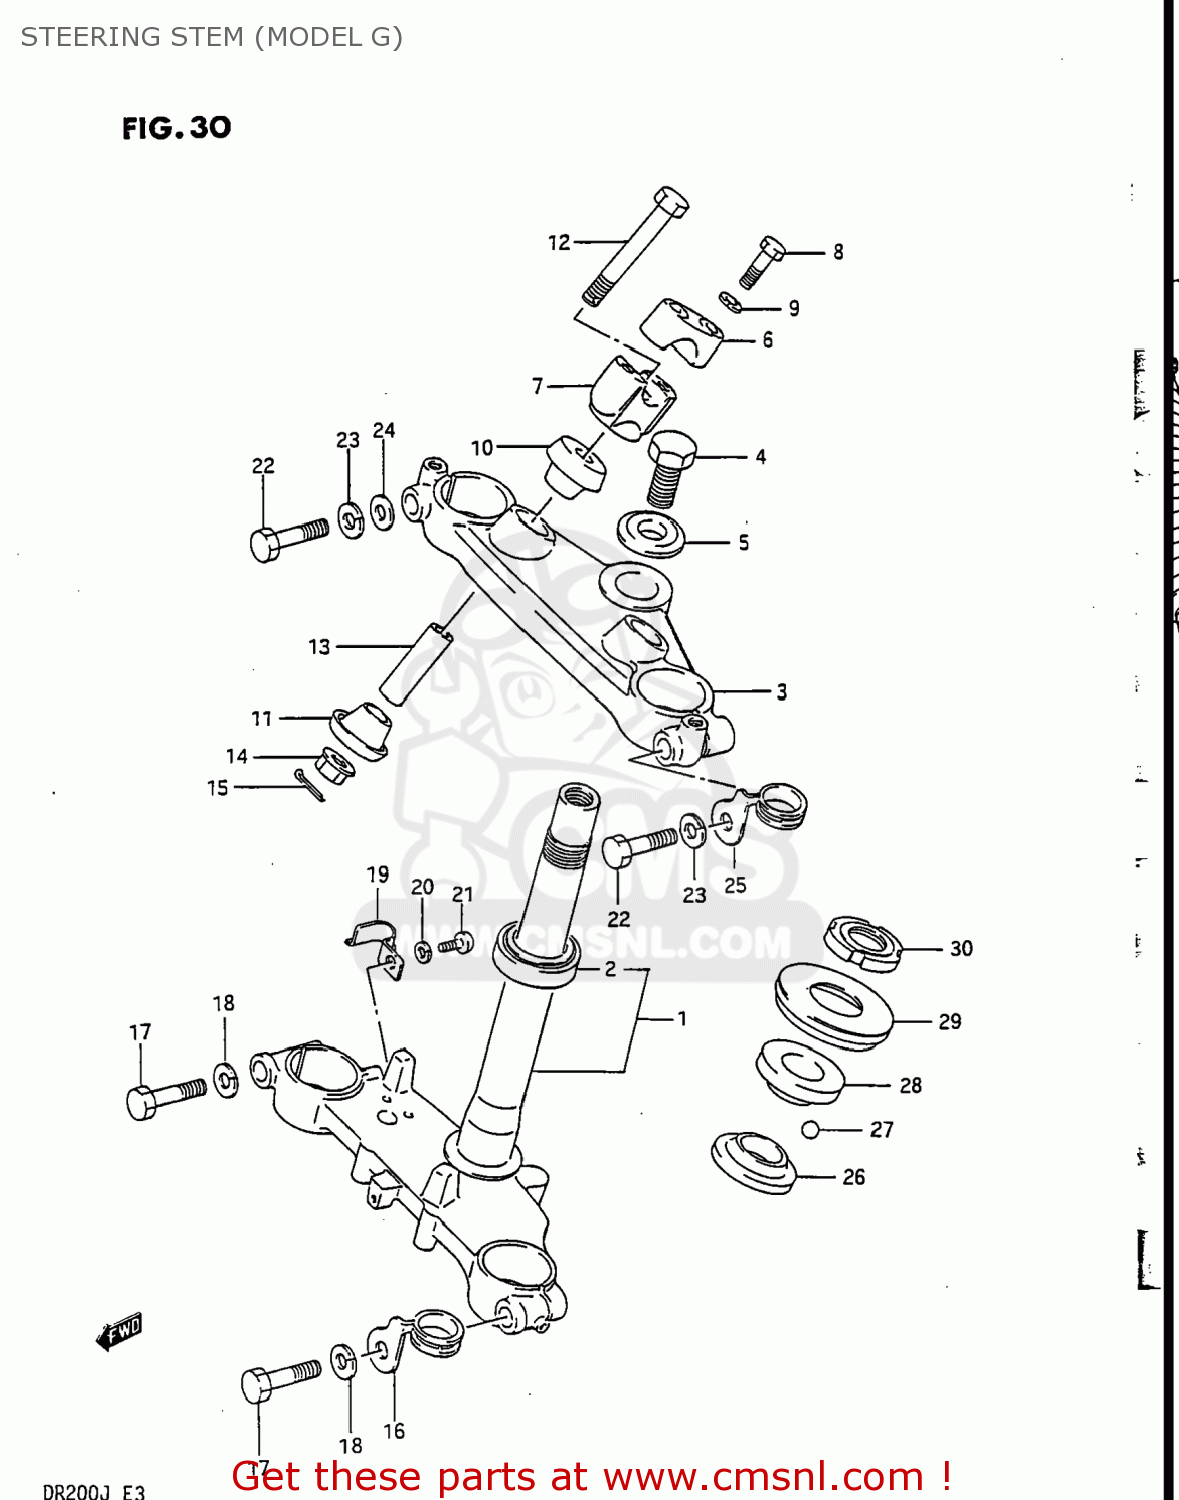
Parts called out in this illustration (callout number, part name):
1	STEM,STEERING
2	BEARING
3	HEAD,STEERING STEM
4	BOLT,STEERING STEM
5	WASHER
6	HOLDER,HANDLEBAR
7	HOLDER,HANDLEBAR,LOWER
8	BOLT
9	LOCK WASHER
10	CUSHION
11	RUBBER,LOWER
12	BOLT
13	SPACER
14	NUT
15	COTTER PIN
16	CLIP,UPPER
17	BOLT,FORK INNER TUBE FITTING
18	LOCK WASHER
19	CLIP
20	WASHER,LOCK
21	SCREW
22	BOLT,FORK INNER TUBE FITTING
23	LOCK WASHER
24	WASHER
25	CLIP,UPPER
26	RACE,STEERING,INNER,UPPER
27	BALL
28	RACE,STEERING,OUTER,UPPER
29	SEAL,STEERING UPR DUST
30	NUT,STEERING STEM
